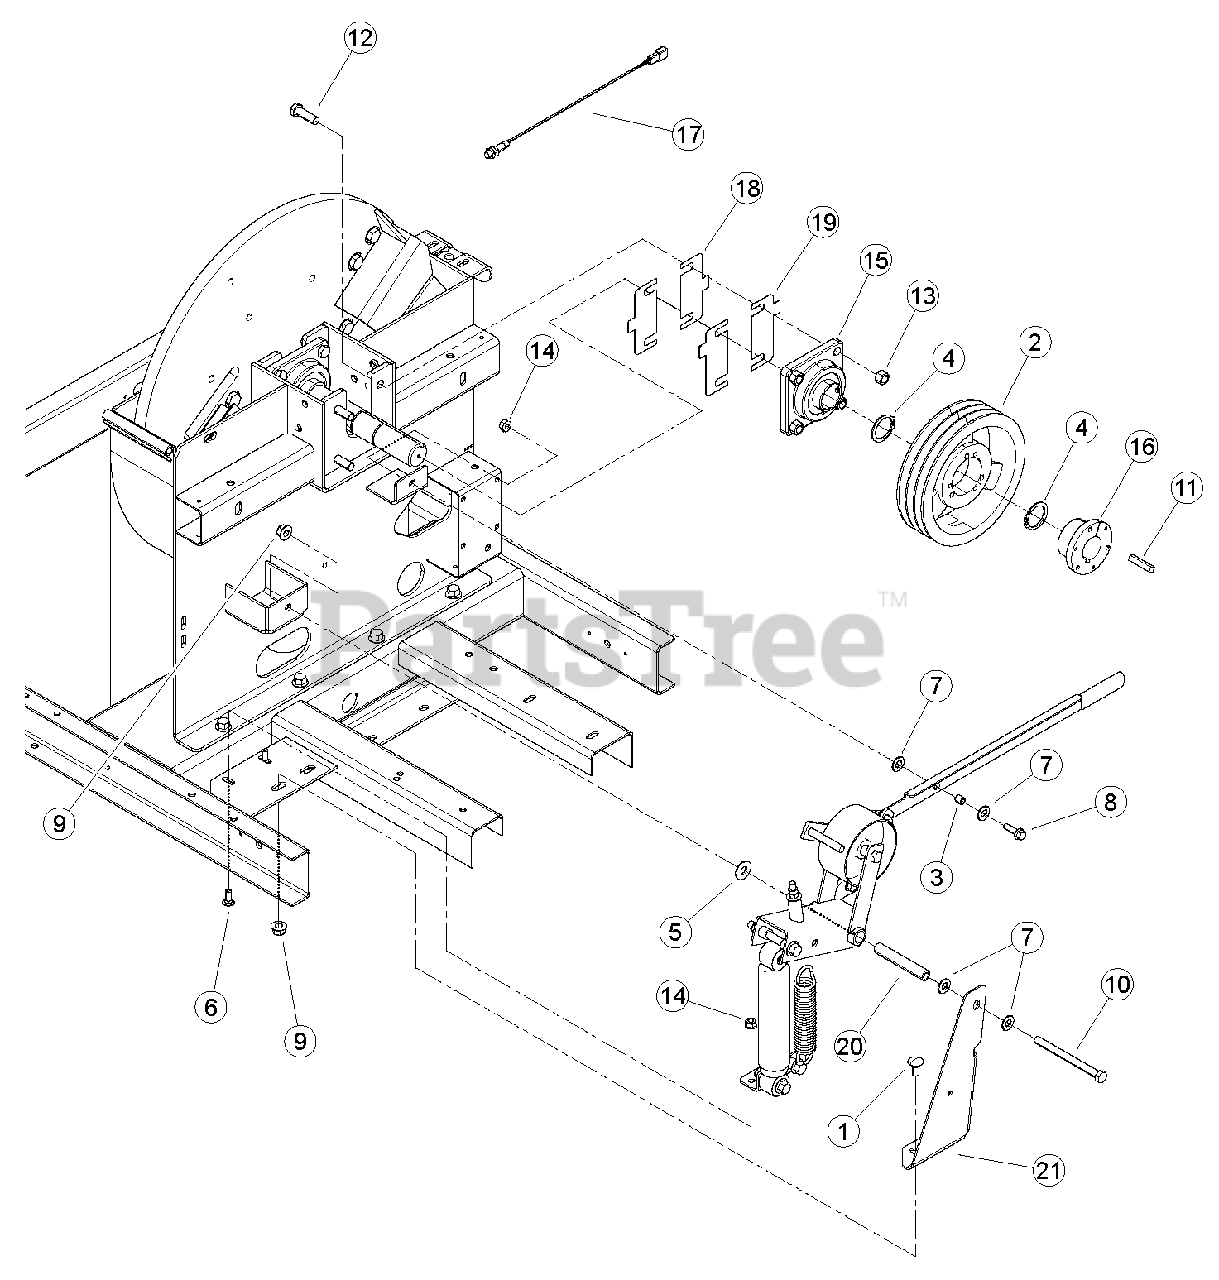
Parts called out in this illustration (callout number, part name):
1	BOLT, 1/2 X 1 CARRIAGE GR5 ZP
2	SHEAVE, 3BQ9.4, SK
3	BUSHING, 3/8 X 1/2 SLEEVE LUBE
4	RING, 1-3/4 EXT HEAVY DUTY SNAP
5	WASHER, 1/2" FLAT ZP
6	BOLT, 3/8 X 1" GR5 CRG NC ZP
7	WASHER, 1/2" SAE FLAT ZP
8	BOLT, 3/8 X 1-1/4 FLANGE NC
9	NUT, 1/2-13 NYLOCK FLANGE
10	BOLT 1/2 X 6 G5 HCS ZP
11	KEY, 3/8" SQ X 2" LG PLAIN
12	BOLT, 9/16 X 1-3/4 HEX GR5 ZP
13	NUT, 9/16 CENTER LOCK GRB ZP
14	NUT, 3/8-16 NYLOCK FLANGE
15	BEARING, 1-3/4 4 BOLT FLANGE
16	BUSHING, SK 1-3/4"
17	SENSOR, M12 PNP PROXIMITY (REPLACEMENT PART)
18	SHIM, 20 GA.
19	SHIM, 16 GA.
20	BUSHING, IDLER PIVOT
21	BRACE, IDLER
